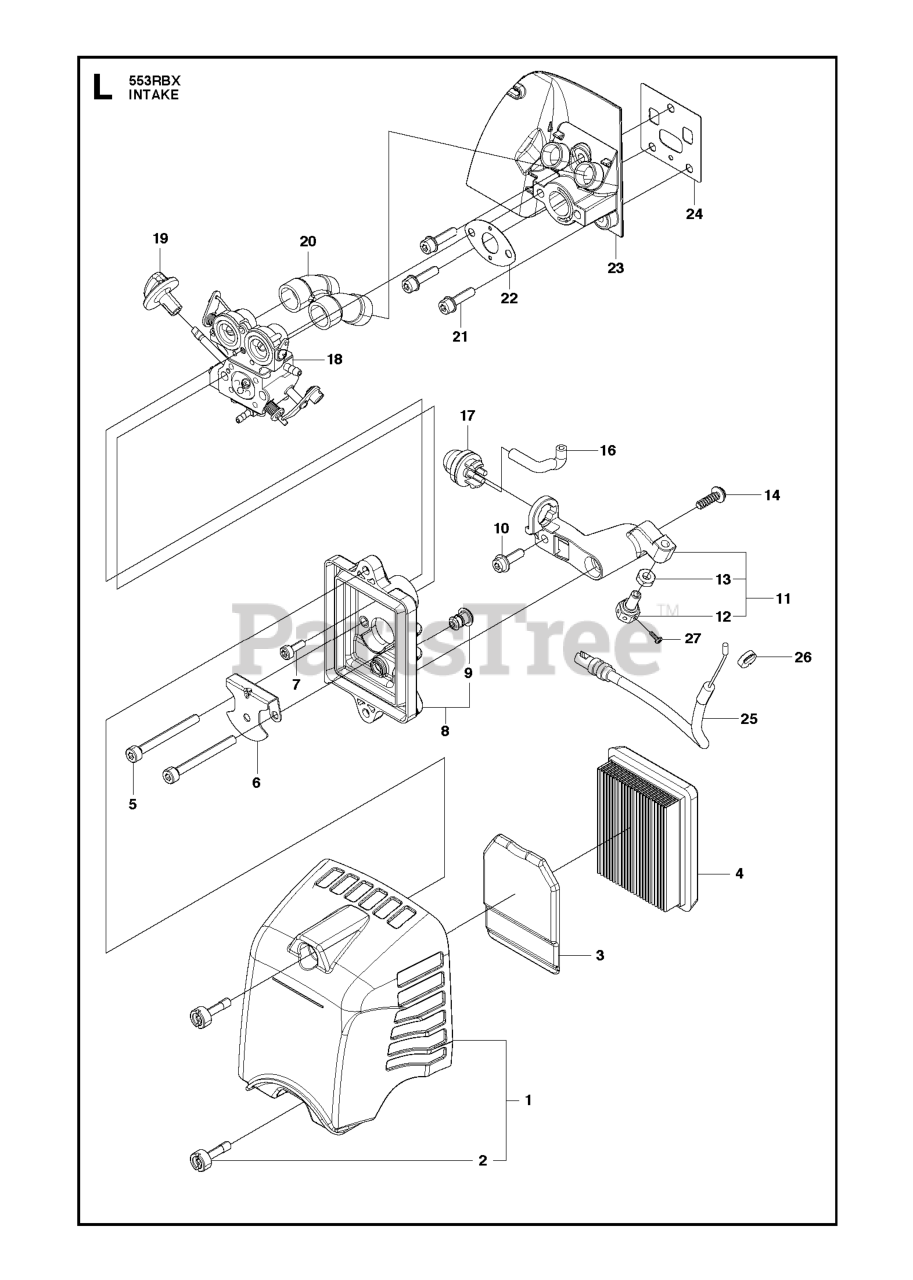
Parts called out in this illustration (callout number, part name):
7	BOLT M4 X 12 T27
12	SCREW CABLE ADJUST
17	PRIMARY BTN
21	BOLT, TORX
